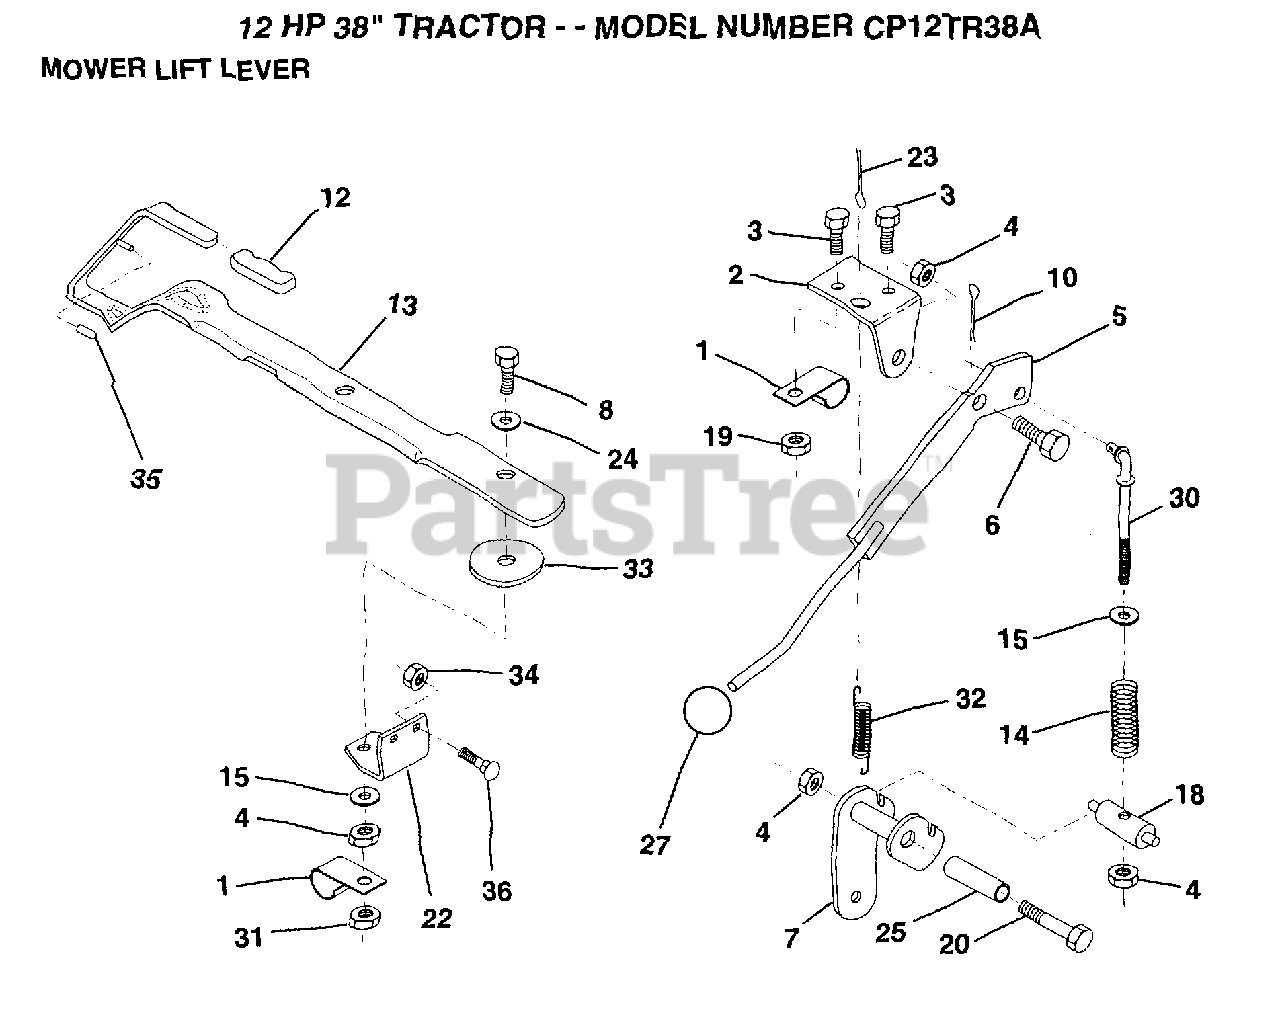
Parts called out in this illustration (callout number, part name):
1	"CLIP,INSULATOR"
2	BRKT CLUTCH
3	BOLT
4	NUT
5	CLUTCH LEVER AS
6	"BOLT, SHOULDER LT"
7	ARM.CLUTCH.ASM
8	BOLT
10	COTTER PIN
12	GRIP HANDLE
13	LEVER LIFT LR
14	COMP CLUTCH SPRNG
15	WASHER HYT
18	TRUNNION
20	BOLT
22	LIFT LEVER BRKT
24	WASHER
25	TUBE SPACER
27	KNOB T(3/8 HOLE)
30	ROD TENSION CLUTC
31	LOCKNUT
32	SPRING EXT
33	WASHER
34	NUT
35	VINYL CAP RED
36	BOLT
